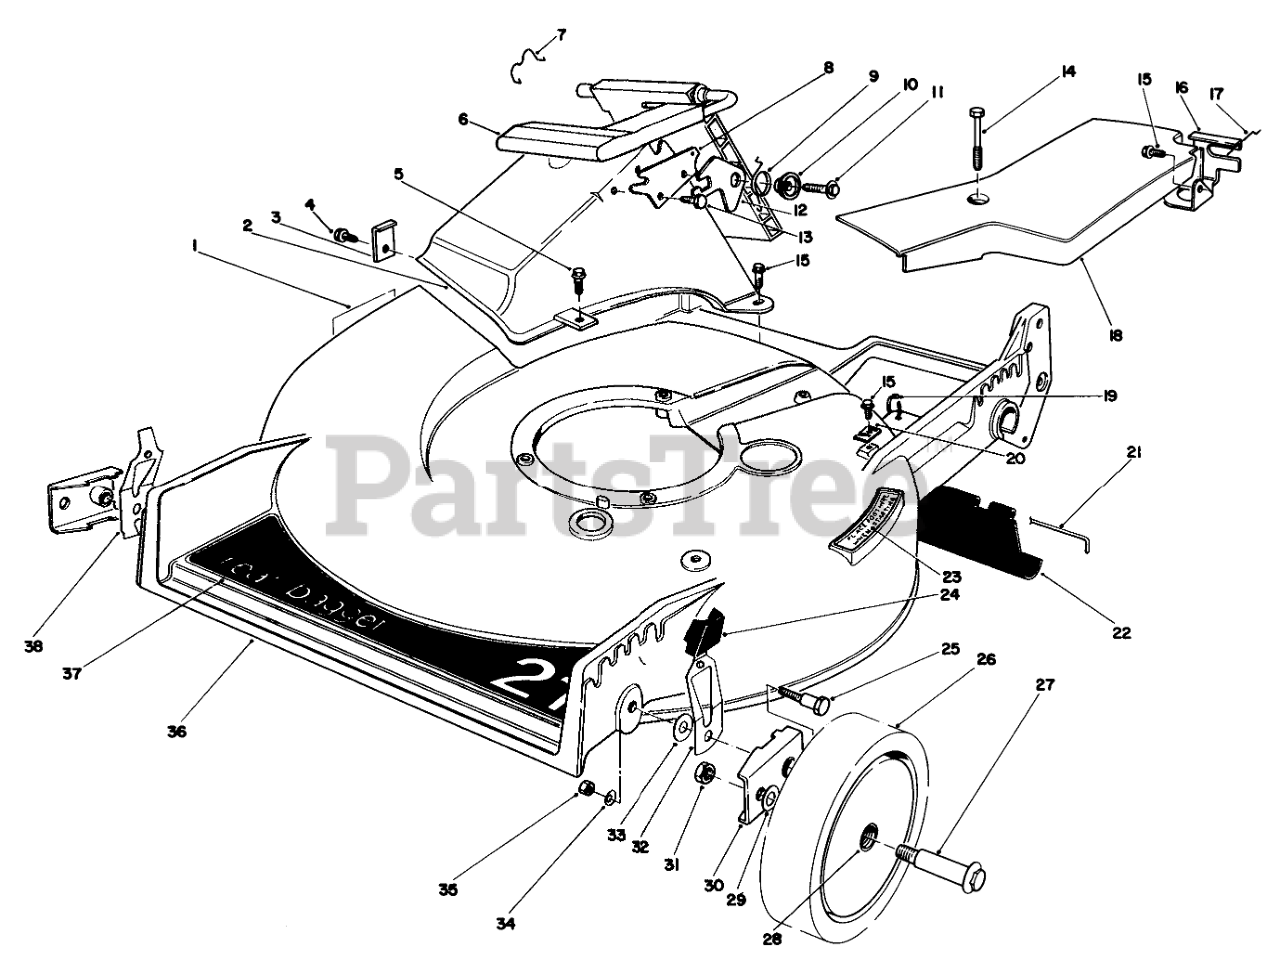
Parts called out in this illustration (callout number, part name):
1	DECAL-DANGER
2	Tunnel Discharge
3	TUNNEL CLIP
4	SCREW
5	SCREW-HWH
6	Discharge Door Assembly
7	DOOR RET SPRING
8	DOOR LATCH PLATE
9	TORSION SPRING
10	DOOR SPACER
11	SCREW-HWH
12	SAFETY LATCH
13	SCREW-PLASTITE
14	SCREW-HHFTF
15	SCREW-HWHTF
16	Bracket-Traction Adj.
17	RETAINER-CABLE
18	Cover-Belt
19	TIE-CABLE
20	Cable Clamp
21	ROD-SHIELD
22	SHIELD-TRAILING
23	STEP PAD DECAL
24	KNOB-ARM
25	PIVOT SCREW
26	Wheel & Tire (Incl. Ref. #17)
27	BOLT-WHEEL
28	BUSHING
29	WASHER
30	HP PIVOT ARM ASM
31	Nut
32	L. HP SPRING ARM ASM
33	WASHER-PIVOT
34	WASHER-BELLEVILLE
35	NUT-LOCK, NI
36	Housing
37	DECK DECAL
38	R HP SPRING ARM ASM
